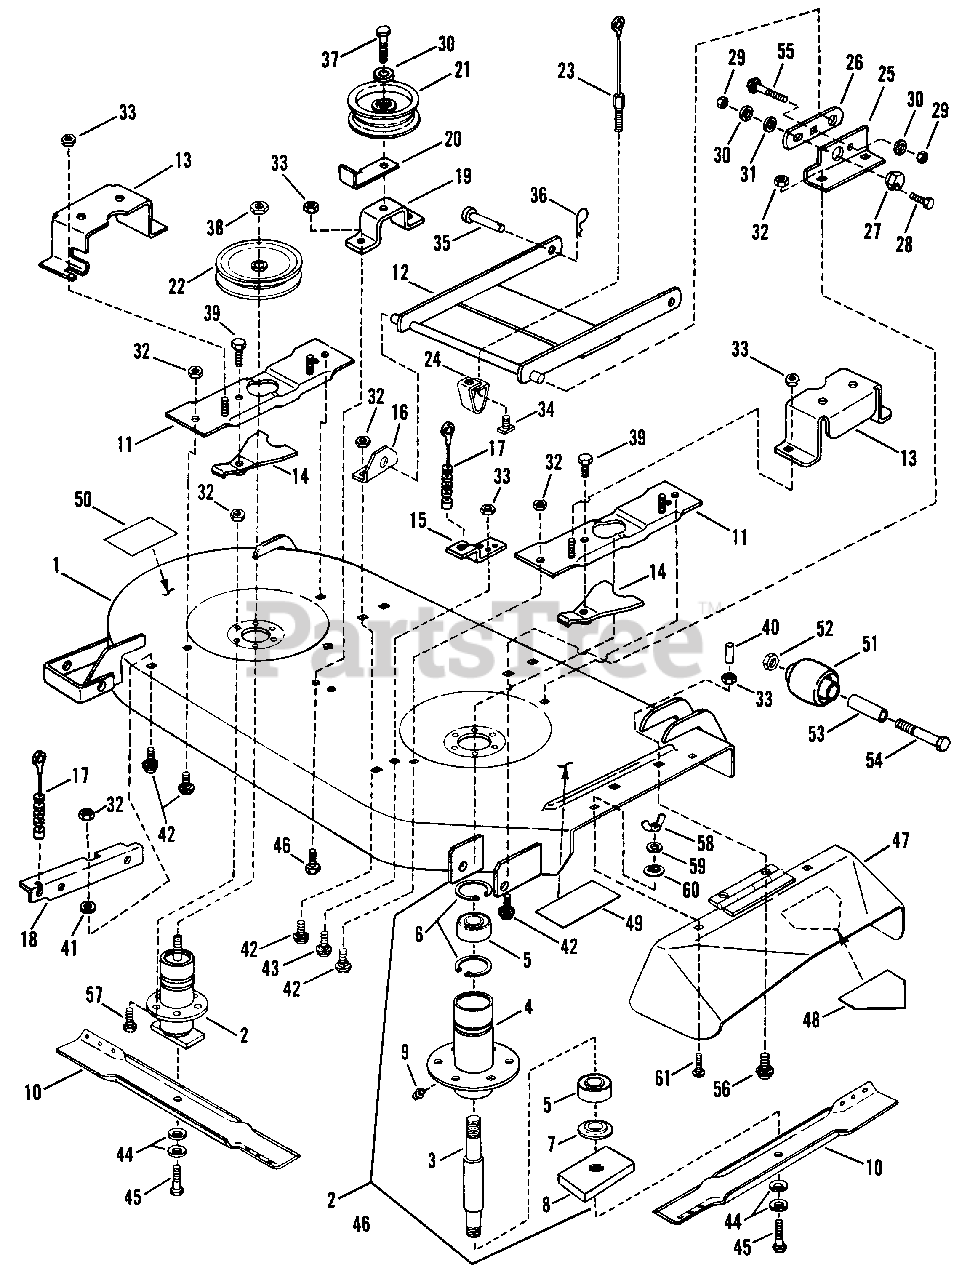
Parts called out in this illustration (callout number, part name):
1	DECK, Mower 41"
2	ASSEMBLY, Spindle
3	SPINDLE
4	HOUSING, Spindle
5	BEARING, Spindle
6	RING, Retaining
7	WASHER, Spindle
8	HOLDER, Blade
9	FITTING, Lube (Press fit for .187 hole-no ball)
10	BLADE, 21" Cutter
11	ASSEMBLY, Rear Support
12	ASSEMBLY, Front Hanger
13	GUARD, Pulley
14	ASSEMBLY, Spindle Lock
15	ASSEMBLY, Chain Support
16	BRACKET, Front Left Hanger
17	CABLE, Support (4.25", 8 Spacers)
18	ASSEMBLY, Rear Support
19	BRACKET, Idler Mount
20	GUIDE, Belt
21	PULLEY, Idler
22	PULLEY, Spindle
23	CABLE, Front Lift 6.125"
24	BRACKET, Front Lift Arm Hanger
25	BRACKET, Front Right
26	LINK, Adjustment
27	RING, Adjustment
28	SCREW, 3/8-16x1" Hex Head Cap
29	NUT, 3/8-16 Hex
30	WASHER, 3/8" Split Lock
31	WASHER, 3/8" Flat
32	NUT, 3/8-16 Hex Flange Lock
33	NUT, 5/16-18 Hex Flange Lock
34	T-NUT, 5/16-18
35	PIN, 1/2x1-3/8" Clevis
36	HAIRPIN, Cotter
37	SCREW, 3/8-16x1-1/2" Hex Cap
38	NUT, 3/4-16 Hex Jam
39	BOLT, 3/8-16x1" Hex Flange Lock
40	CAP, Vinyl
41	WASHER, 7/16 Flat
42	BOLT, 3/8-16x3/4" Carriage
43	BOLT, 5/16-18x3/4 Carriage
44	WASHER, 13/32x1-13/32" Dia. Cone
45	SCREW, 3/8-24x1-1/4" Hex Cap
46	BOLT, 5/16-18x3/4" Hex Flange Lock
47	DEFLECTOR, Side Chute
48	DECAL, Danger
49	DECAL, Caution
50	DECAL, Caution
51	WHEEL, Gage
52	LOCKNUT, 3/8-24 Hex
53	SPACER
54	SCREW, 3/8-24x3-3/4" Hex Hd. Cap
55	BOLT, 3/8-16x3/4" Short Neck Carriage
56	BOLT, 5/16-18x1" Short Neck Carriage
57	BOLT, 3/8-16x3/4" Hex Flange Lock
58	WING-NUT, 5/16-18
59	WASHER, 5/16 Split Lock
60	RETAINER, 5/16 Bolt
61	BOLT, 5/16-18x5/8" Carriage
